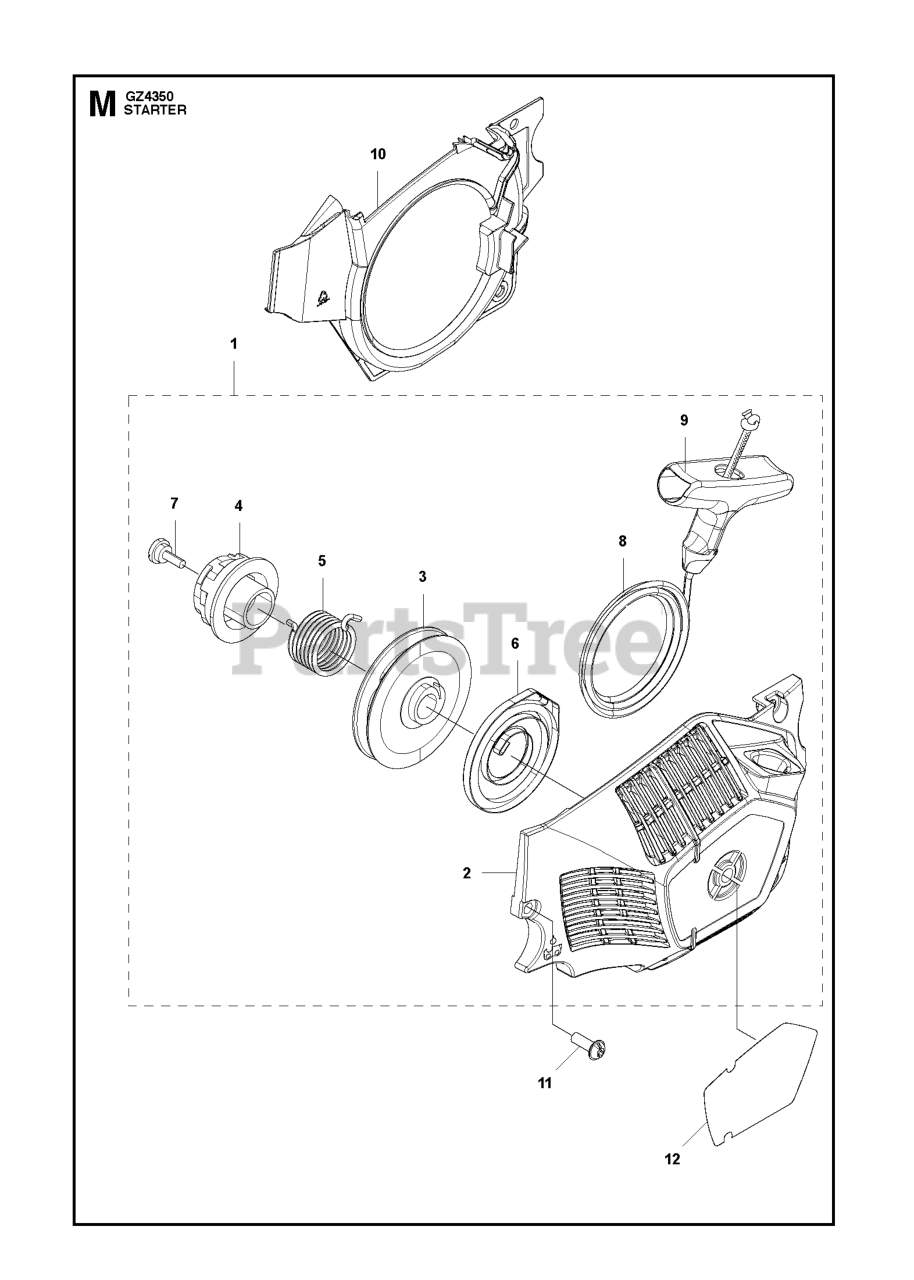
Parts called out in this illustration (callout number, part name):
1	STARTER ASSY
2	STARTER HOUSING COMP
4	STARTER PULLEY CAM
6	SPRING CASSETTE ASSY OLD P/N
9	STARTER HANDLE
10	AIR CONDUCTOR COOLING
11	SCREW M5 X 14
12	DECAL STARTER GZ4350-US
